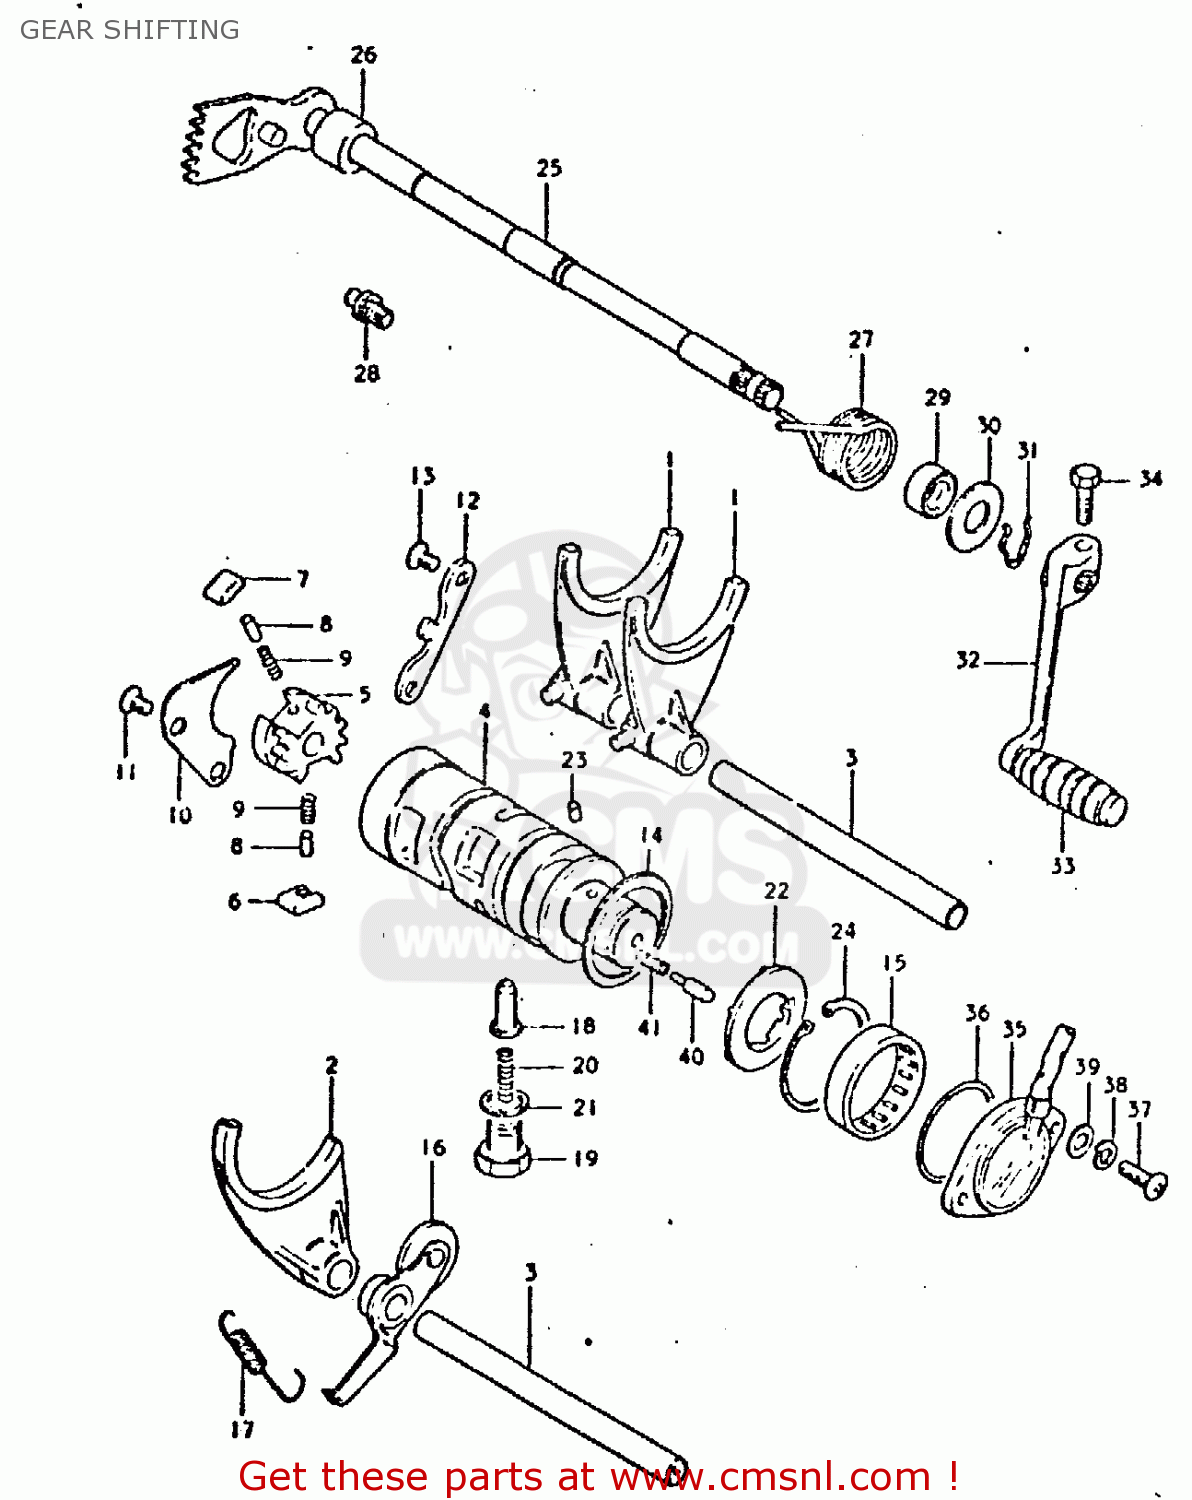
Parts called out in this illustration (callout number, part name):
1	FORK,GEAR SHIFT NO.1
2	FORK,GEAR SHIFT NO.3
3	SHAFT,GEAR SHIFT FORK
4	CAM,GEAR SHIFT
5	RETAINER,GEAR SHIFT CAM
6	PAWL,GEAR SHIFT NO.1
7	PAWL,GEAR SHIFT NO.2
8	PIN(5X8)
9	SPRING
10	LIFTER,GEAR SHIFT PAWL
11	SCREW
12	GUIDE,GEAR SHIFT CAM
13	SCREW
14	WASHER(40X45X1)
15	BEARING(25X32X12)
16	STOPPER,GEAR SHIFTING
17	SPRING
18	STOPPER,GEAR SHIFT CAM NO.2
19	HOLDER,GEAR SHIFT CAM STOP SPR
20	SPRING
21	GASKET(14X19.2X2) (NAS)
22	PLATE,GEAR SHIFT CAM STOPPER
23	PIN 4X6
24	CIRCLIP
25	SHAFT,GEAR SHIFT
26	SPACER
27	SPRING
28	STOPPER,GEAR SHIFT CAM
29	OIL SEAL
30	WASHER (12.5X27X1.6)
31	SPRING,RETAINER
32	LEVER ASSEMBLY,GEAR SHIFTING
33	RUBBER,GEAR SHIFT PEDAL
34	BOLT
35	TERMINAL BASE ASSY,GEAR SHIFT
36	O-RING (D:2.4 ID:26.2)
37	SCREW 5X20
38	LOCK WASHER
39	WASHER
40	PIN(5X15.5)
41	SPRING
